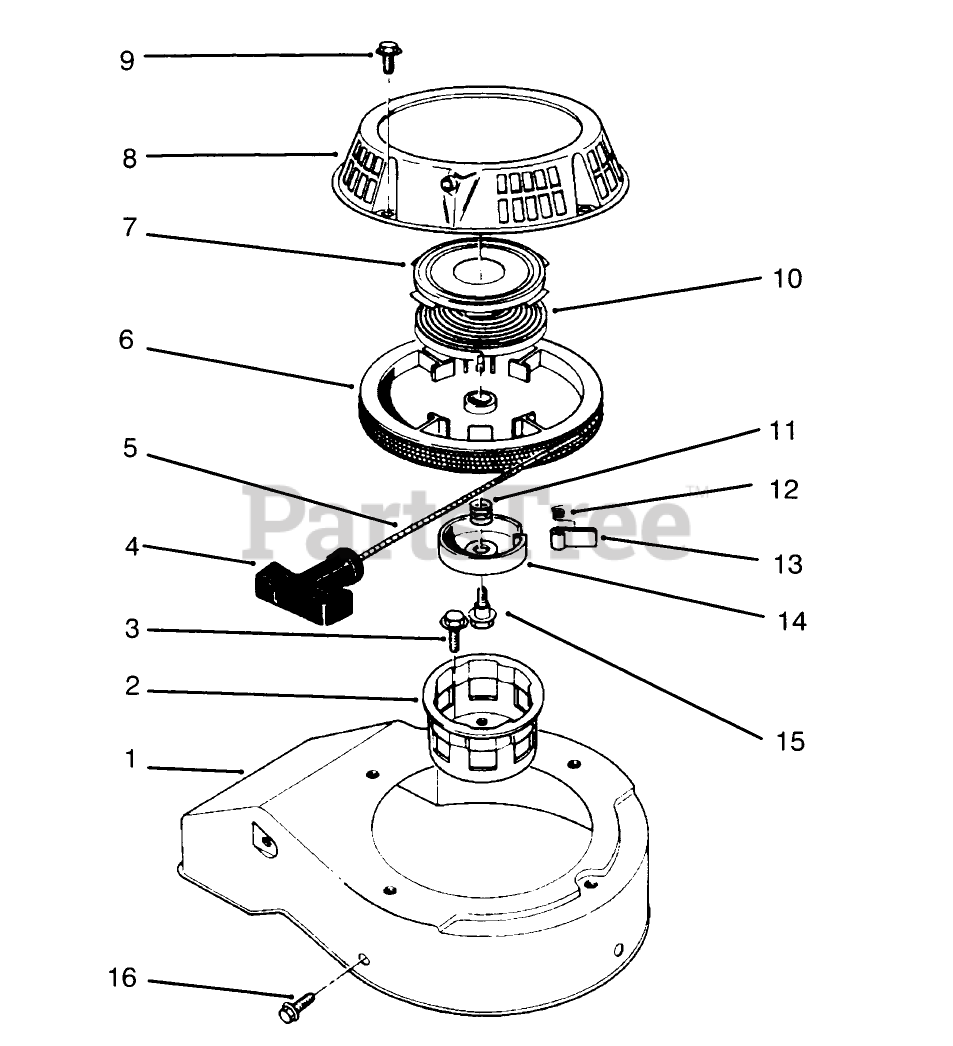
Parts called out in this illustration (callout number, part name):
1	Cover-Cooling Fan
2	PULLEY-CUP, STARTER
4	HANDLE-RECOIL
5	ROPE-STARTER
7	Retainer-Spring,Recoil
8	CASE-STARTER
9	SCREW-HHF
10	Spring-Recoil
11	SPRING
12	SPRING
14	RETAINER
